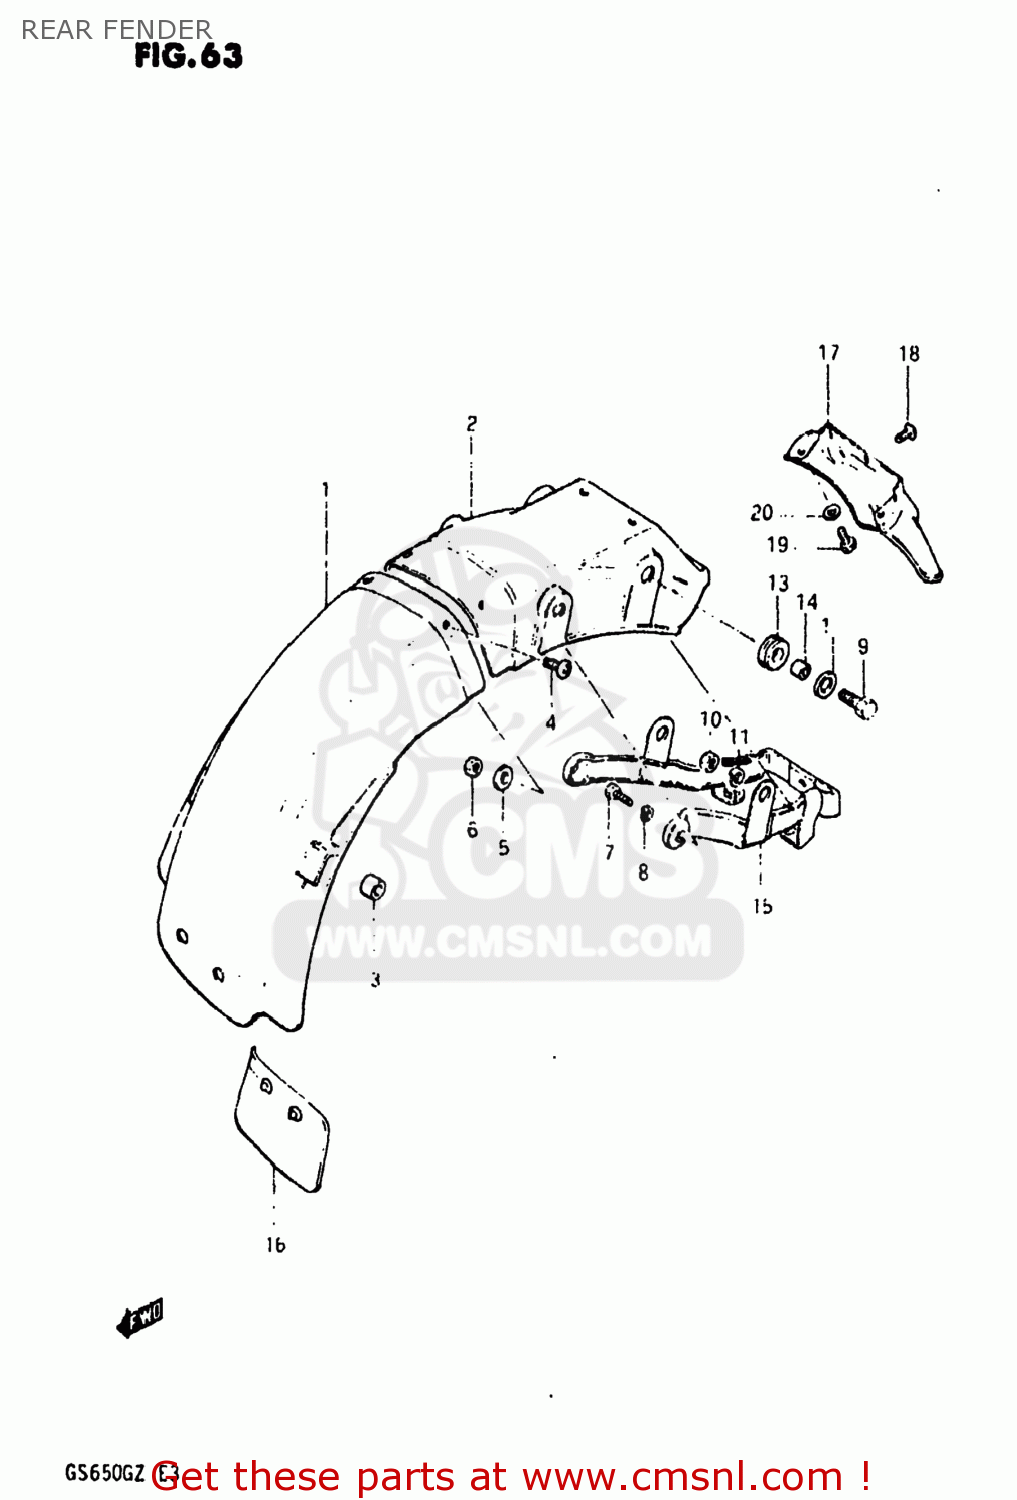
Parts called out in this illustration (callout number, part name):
1	FENDER,REAR
2	BODY,REAR FENDER,REAR
3	CUSHION
4	SCREW
5	WASHER (5.5X16X1.2)
6	NUT
7	BOLT, UPPER
8	LOCK WASHER
9	BOLT (8X30)
10	NUT
11	LOCK WASHER
12	WASHER
13	CUSHION
14	SPACER (8.2X12X7.5)
15	REINFORCEMENT,REAR FENDER
16	GUIDE,RR FENDER MUD
17	EXTENSION,RR FENDER
18	SCREW
19	BOLT, UPPER
20	WASHER (6.5X20X1.2)
